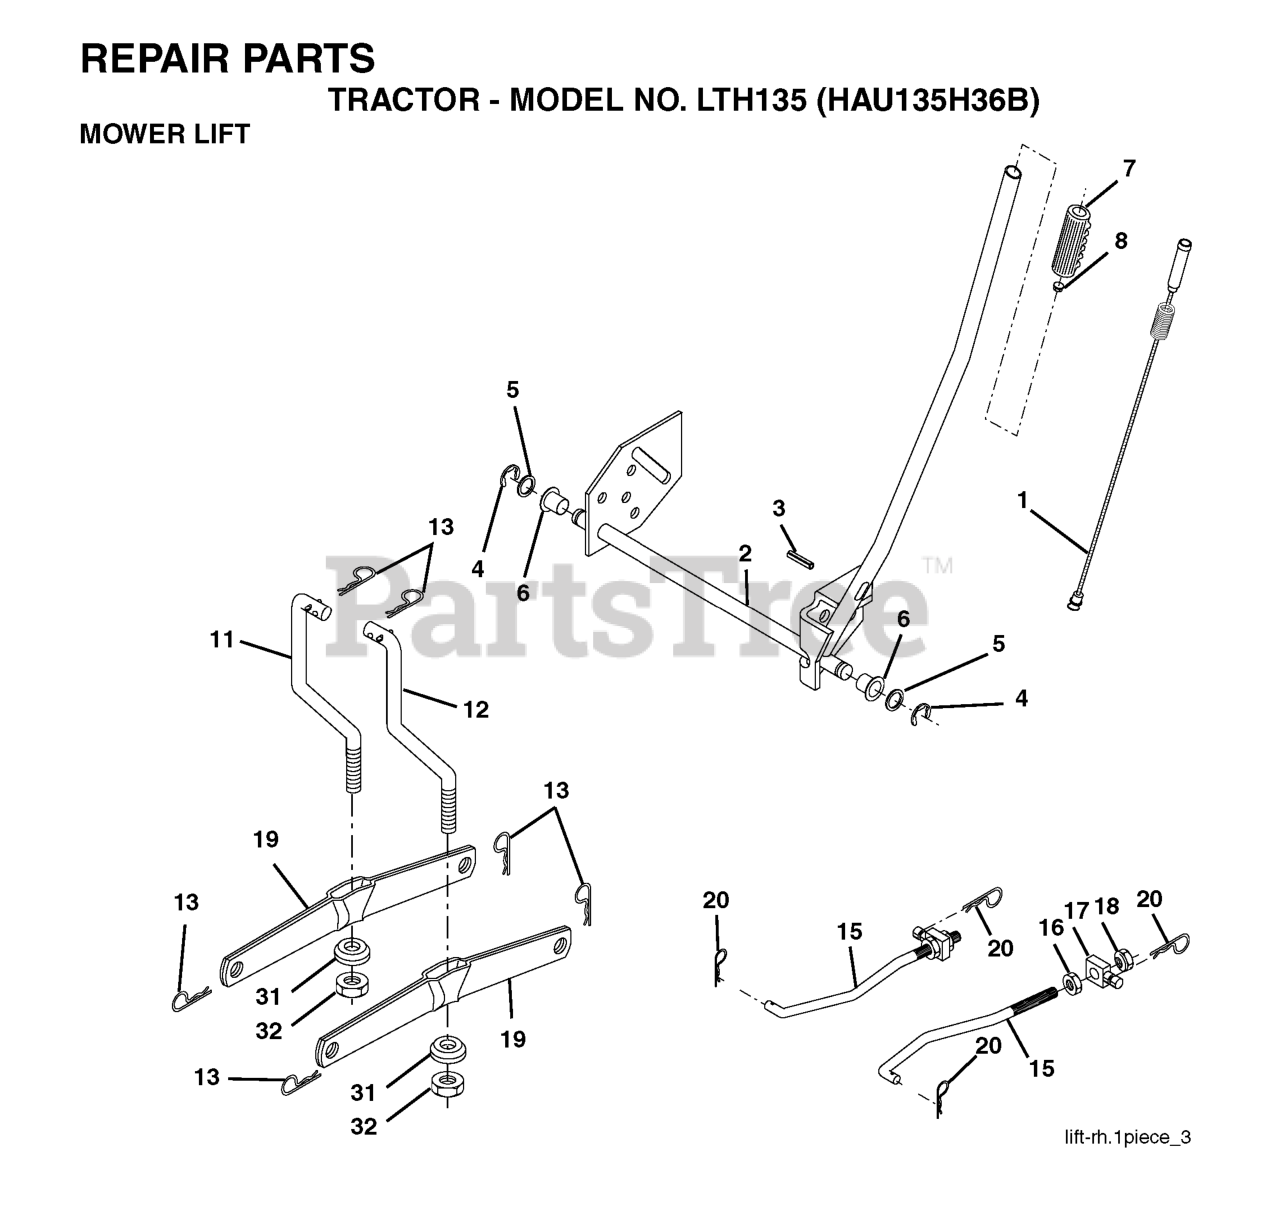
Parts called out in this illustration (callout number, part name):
1	WIRE ASM INNER W/ PLUNGER LT
2	SHAFT ASM R HANDLE
3	PIN GROOVE.
4	RETAINING RING LT
6	BEARING.NYLON
8	PLUNGER BUT KIT
11	LINK LIFT LH
12	LINK LIFT RH
13	RETAINER-SPRNG RB
15	LINK.SUSPENSION.FRONT
16	NUT.HEX.JAM.1/2-13
18	NUT.LK.W/WSH.1/2.
19	ARM.REAR.SUSPENSION
20	SPRING RETAINER
31	BEARING.PIVOT.LIFT
32	NUT CROWNLOCK 3/8-24
